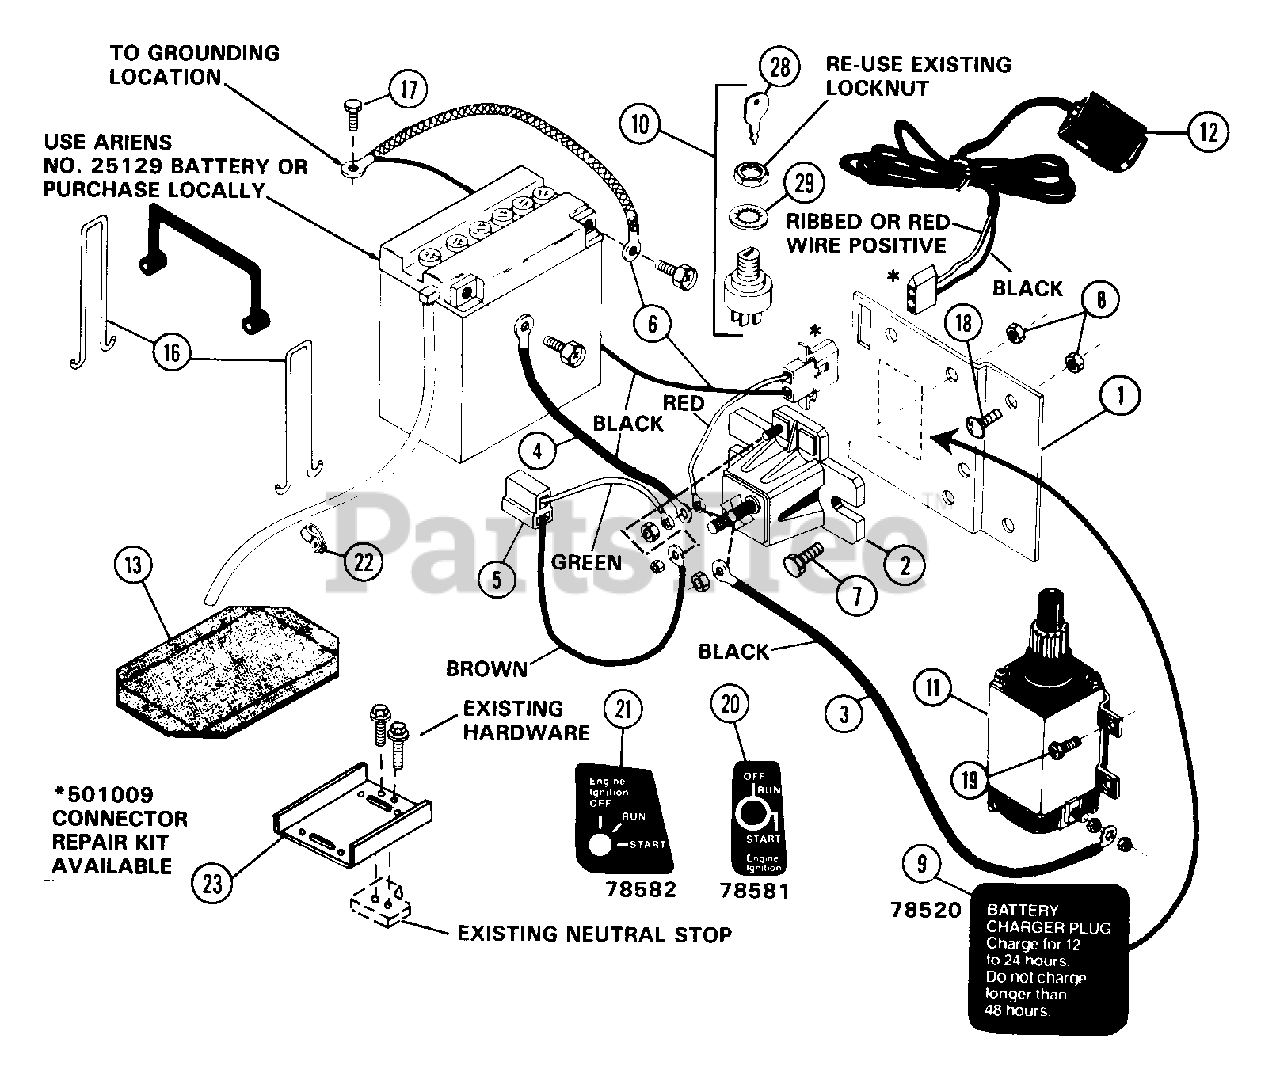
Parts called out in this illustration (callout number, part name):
1	BRACKET SOLENOID
2	SOLENOID
3	GROUND CABLE
4	GROUND CABLE
5	WIRING HARNESS SWITCH
6	WIRING HARNESS BATTERY CHARGER
7	BLT-HEX .25-20X.50 PL GR2
8	NUT-LK-CTR .250-20 PL
9	CHARGING DECAL
10	IGNITION SWITCH ASSEMBLY
12	BATTERY CHARGER
13	RUBBER PAD
15	BATTERY STRAP
16	HOOK
17	SCR-TAP 10-24X.375 CRPH 1A
18	BLT-RDHDSQNK .25-20X.62 PL
19	SCR-CAP CR SEMS .25-20X.50 PL
20	ELECTRIC START DECAL
21	ENGINE IGNITION DECAL
23	BATTERY TRAY
24	WSHR-LK .312X.097 PL HVY
25	NUT-JAM .312-24 PL
26	WSHR-LK 10X.047 MED PL
27	NUT 10-32 PL
28	KEYS
29	WSHR-LK-INT .625X.045 PL
